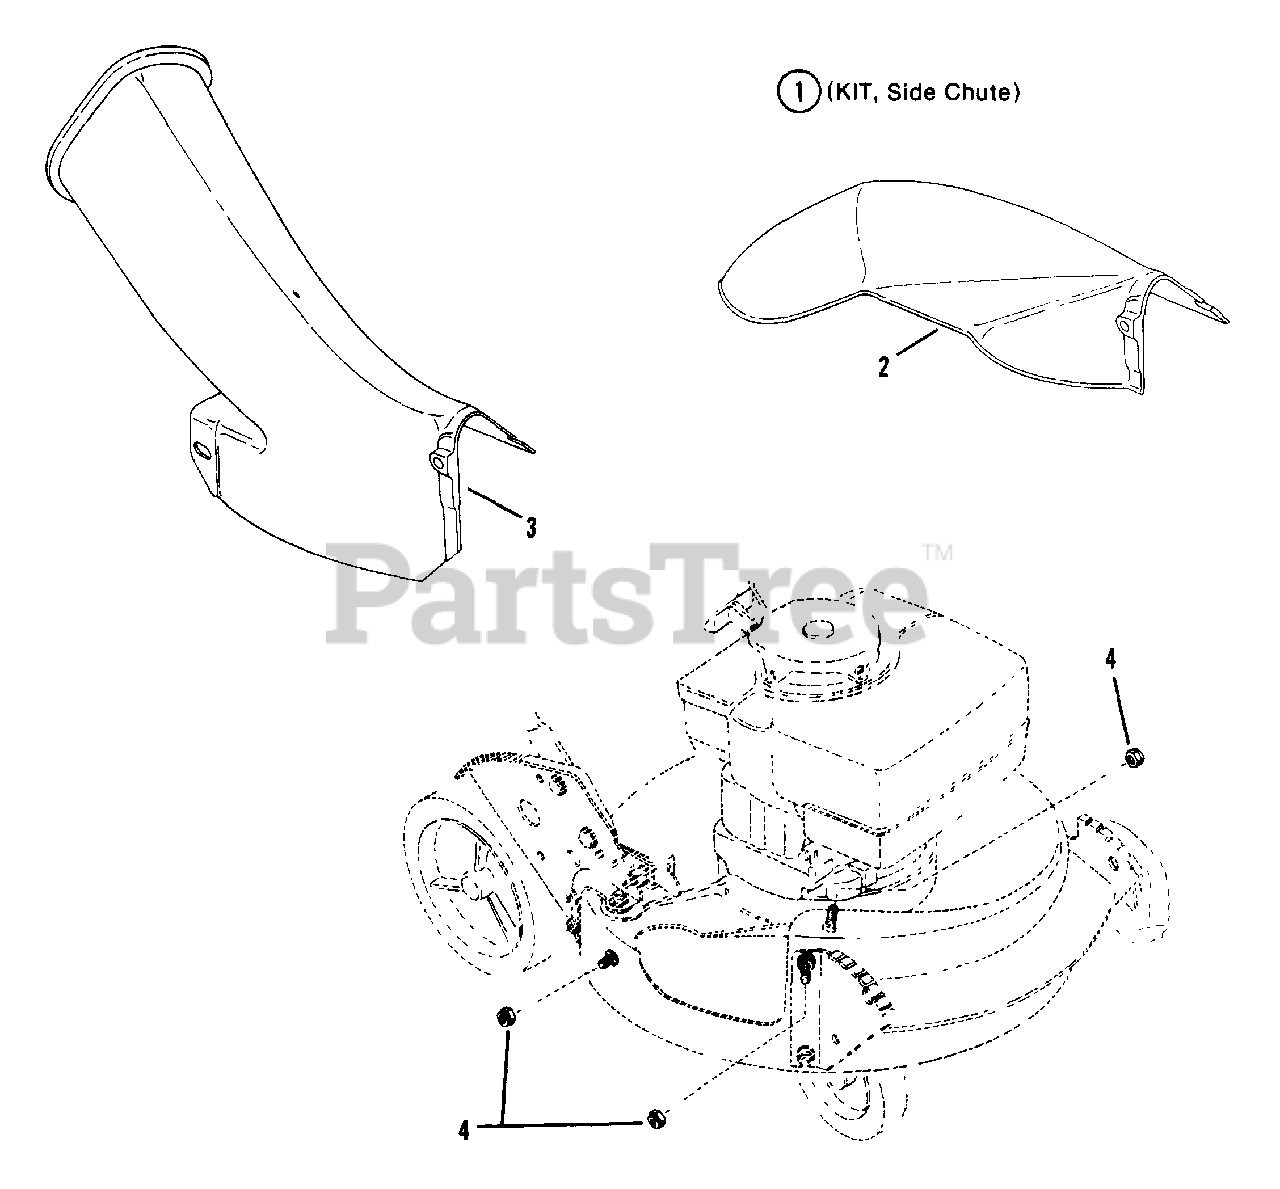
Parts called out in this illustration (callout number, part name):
1	KIT, Side Chute
2	CHUTE, Side
3	ADAPTER, Grass Bag Deck (Replaces 1-9942)
4	NUT, 5/16-18 Hex Flange Lock
